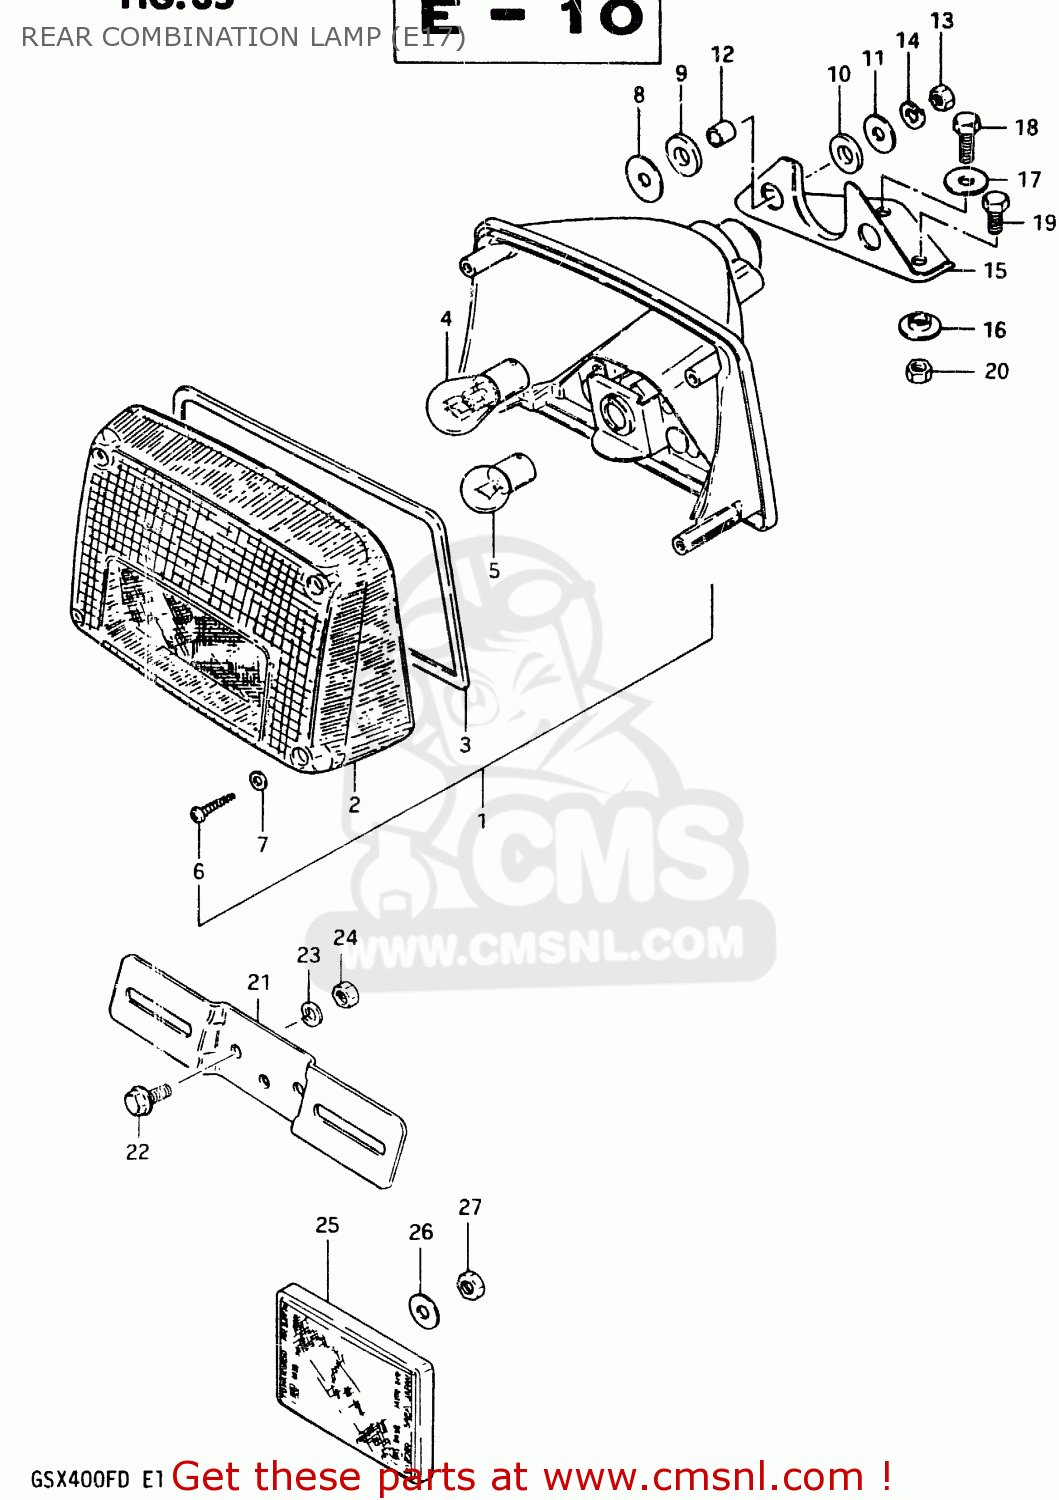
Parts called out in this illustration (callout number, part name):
1	LAMP ASSY, REAR COMBINATION
2	LENS
3	GASKET (NAS)
4	BULB 12V21/5W
5	BULB
6	SCREW,REAR COMBINATION LAMP
7	GASKET (NAS)
8	WASHER
9	CUSHION
10	CUSHION
11	WASHER(6,5X22X1.6)
12	SPACER(6.1X9X7.5)
13	NUT
14	LOCK WASHER
15	BRACKET,RR COMBINATION LAMP
16	WASHER
17	WASHER
18	BOLT
19	BOLT, UPPER
20	NUT 6MM
21	BRACKET, LICENSE PLATE
22	BOLT
23	LOCK WASHER
24	NUT
25	REFLEX REFLECTOR,RR
26	WASHER(5.2X16X1)
27	NUT
